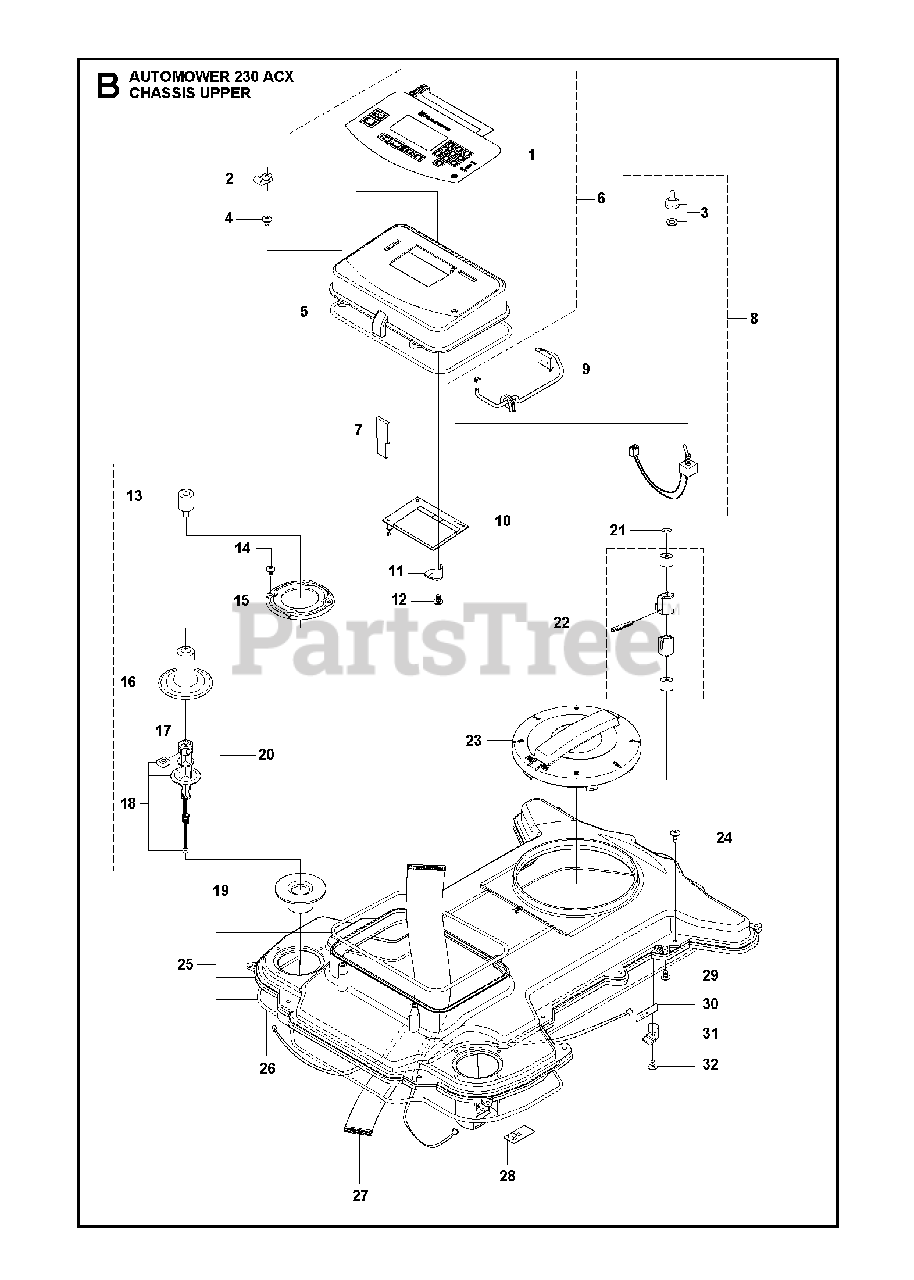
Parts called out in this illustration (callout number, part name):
1	KEYBOARD
2	CABLE CLAMP
3	RUBBER HOOD ON/OFF SWITCH
4	SCREW ITXPANT
5	SEALING STRIP
5	SEALING STRIP G2-2 DISPLAY CO
6	DISPLAY COVER 230ACX
8	BRAKER
9	SWITCH KIT
12	SCREW 14MM
13	DAMPER RUBBER
14	SCREW 14MM
15	RING FASTENER
16	RUBBER GAITERS
17	NUT
18	COLUMN ASSY
19	MOVEMENT LIMITER
20	COLUMN REAR COLLISION COLUMN
21	LOCKWASHER
22	LIFT SENSOR COMP
23	STEERING WHEEL
24	SCREW ITXPANT
25	CHASSIS UPPER
26	SEALING STRIP
26	SEALING STRIP G2-2 CHASSIS
27	MAIN RIBBON HARNESS
28	PRINTED CIRCUIT ASSY
30	PRINTED CIRCUIT ASSY
32	SCREW 14MM
